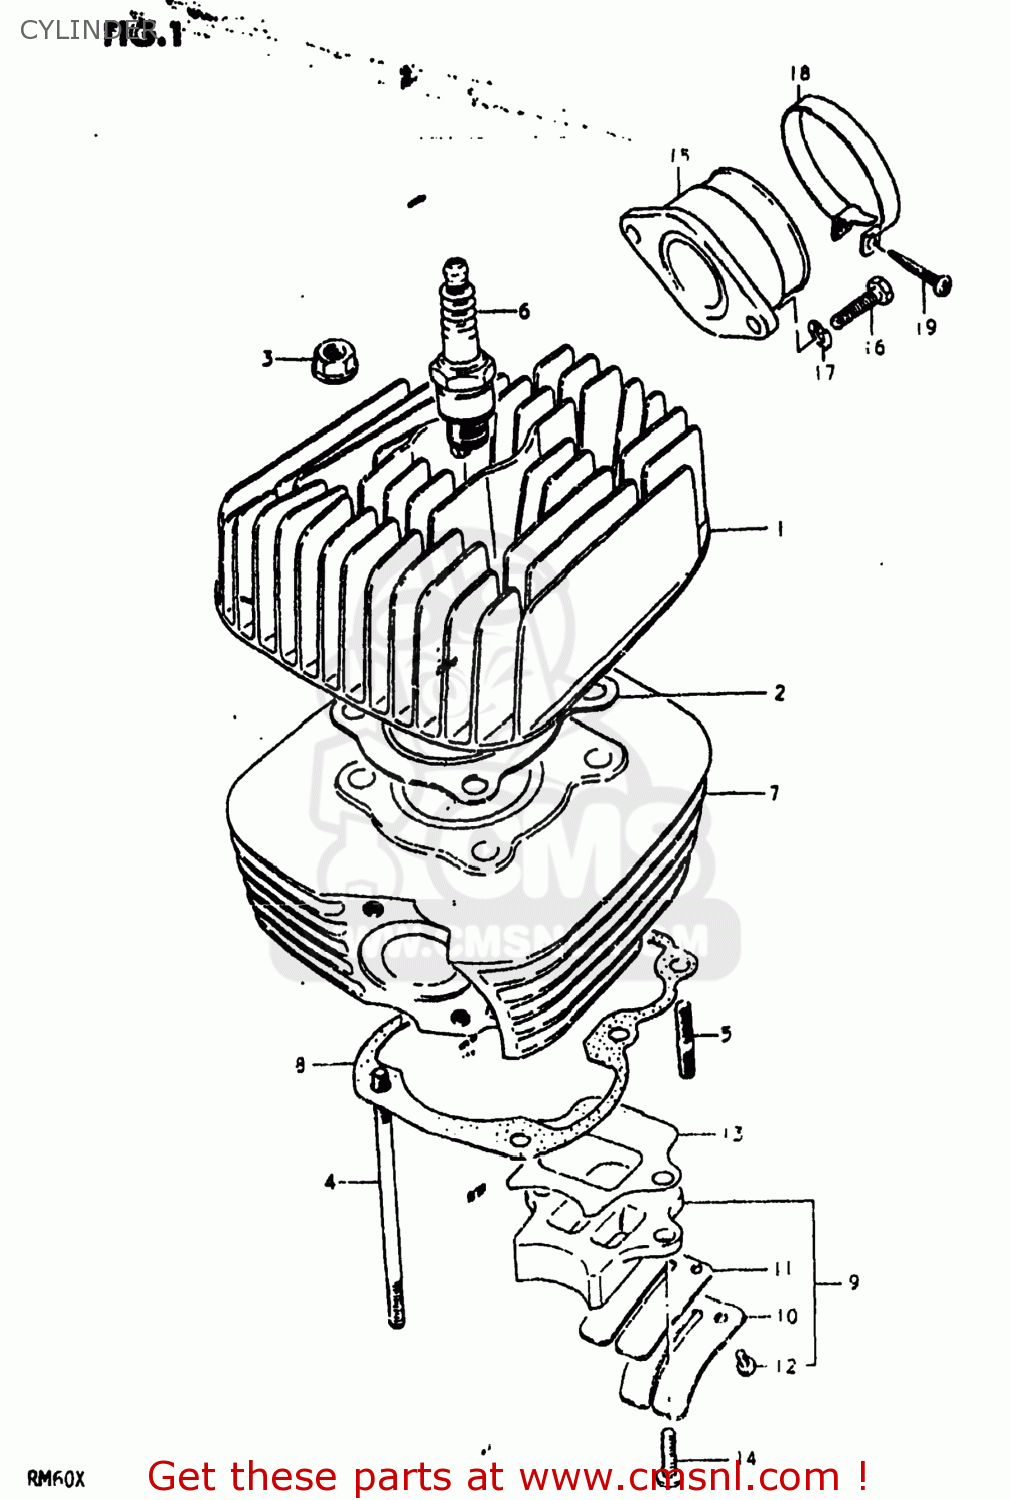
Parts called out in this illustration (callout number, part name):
1	HEAD,CYLINDER
2	GASKET,CYLINDER HEAD (NAS)
3	NUT
4	STUD
5	STUD BOLT
6	SPARK PLUG
7	CYLINDER
8	GASKET,CYLINDER (MCA)
9	VALVE ASSY,REED
10	STOPPER,REED VALVE
11	VALVE,REED
12	SCREW,REED VALVE
13	GASKET,REED VALVE (MCA)
14	SCREW
15	PIPE,INTAKE
16	BOLT, UPPER
17	LOCK WASHER
18	CLAMP
19	SCREW
